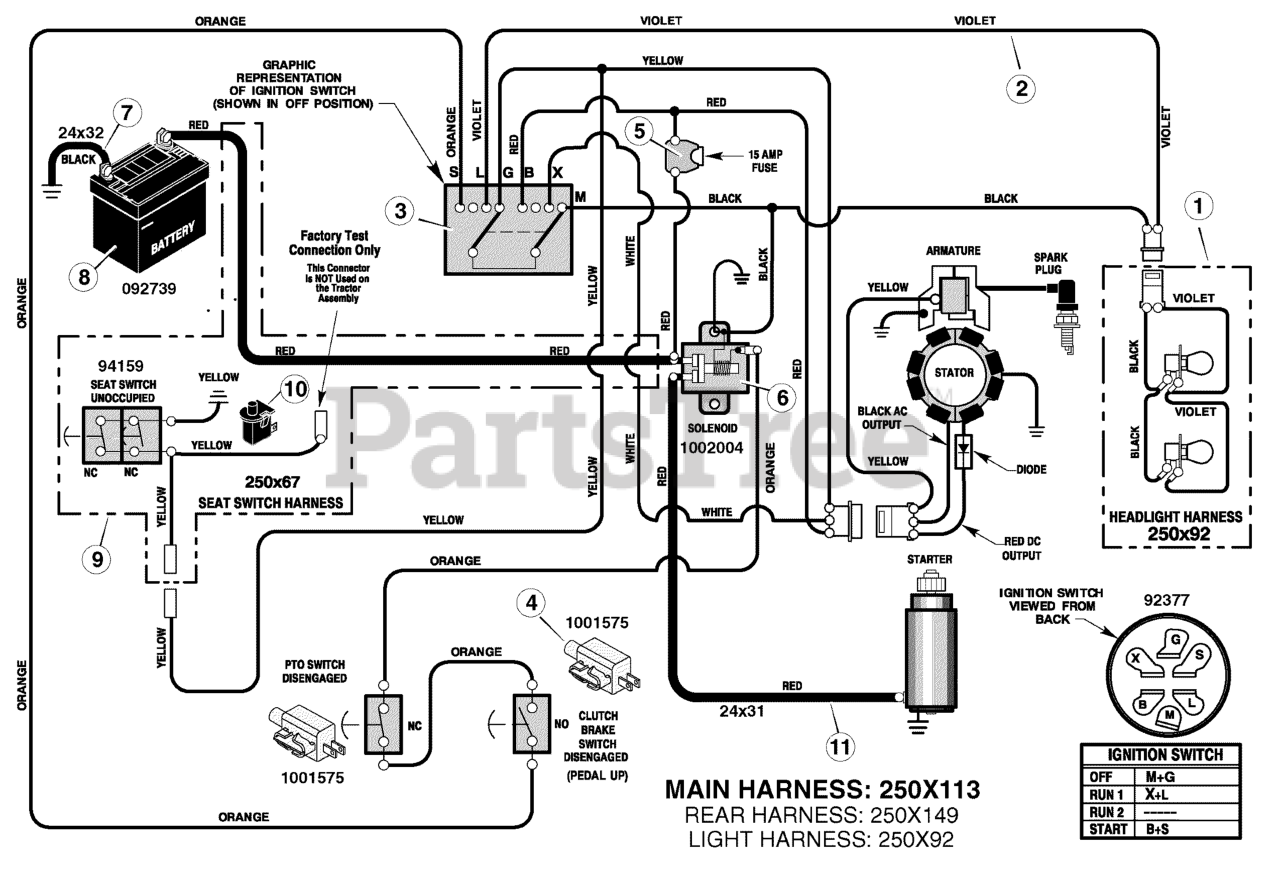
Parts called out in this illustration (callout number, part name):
1	Harness, Light Wire
1	Socket, Light
1	Bulb, Light
2	Harness, Chassis Wire
3	Switch, Ignition
3	Key, Ignition
3	Nut, Hex
3	Cap, Ignition
4	Switch, Limit
5	Holder, Fuse
6	Solenoid
6	Screw, Mounting
6	Locknut
7	Cable, Battery Ground
7	Screw, Ground Cable
8	Battery
8	Bolt, Carriage
8	Wingnut
8	BOOT, Battery Terminal, Positive
9	Harness, Seat Switch Wire
10	Switch, Seat Sensor
